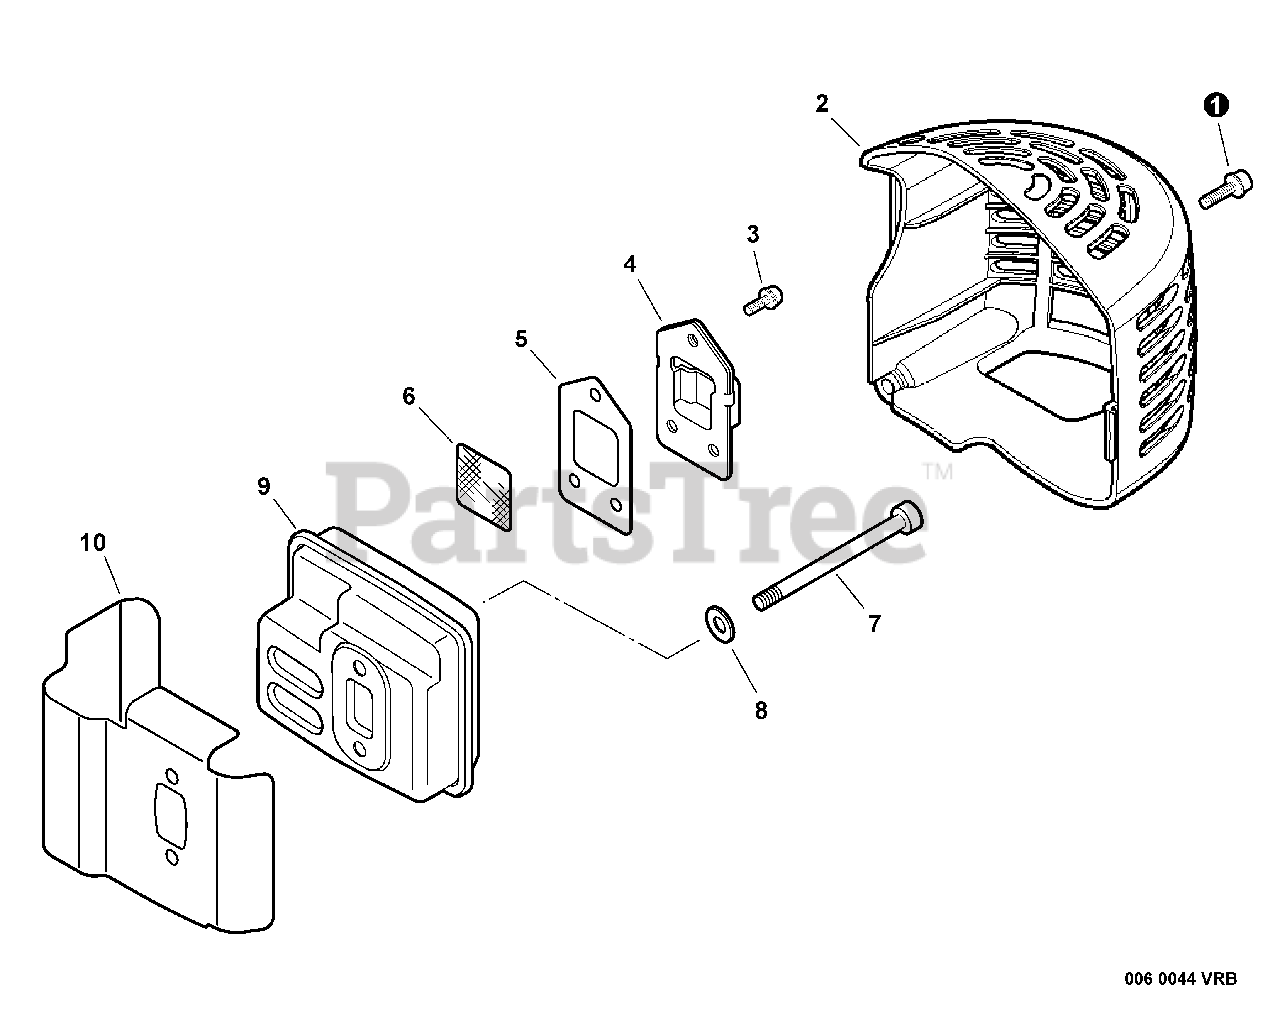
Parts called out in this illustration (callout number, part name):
1	BOLT 5×16
2	COVER, MUFFLER
3	SCREW 4×10
4	GUIDE, EXHAUST
5	GASKET, EXHAUST
6	SCREEN, SPARK ARRESTER
7	BOLT 5×55
8	WASHER, FLAT 5.5×10×0.8
10	HEAT SHIELD, EXHAUST
